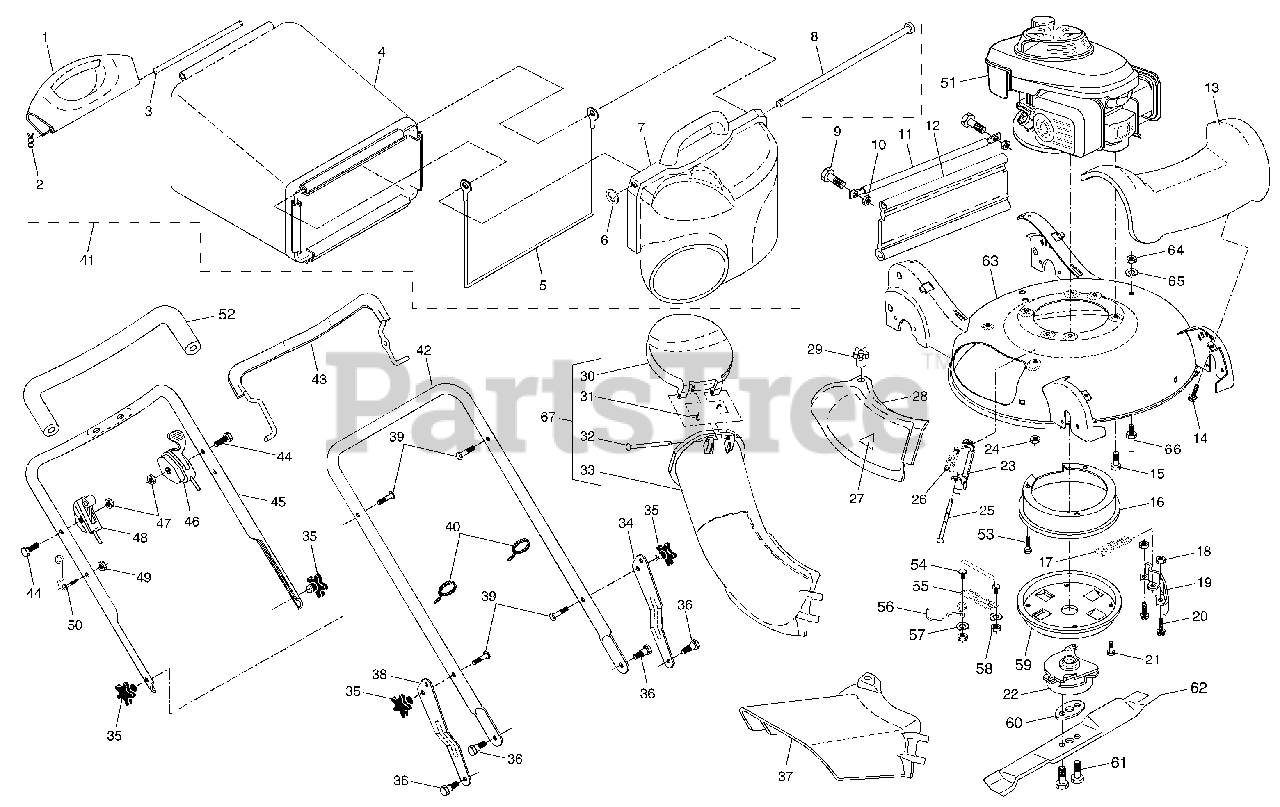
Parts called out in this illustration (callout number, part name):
1	Handle, Grassbag, Rear
2	Hairpin Cotter
3	Rod, Rear Handle, Grassbag
4	Grassbag
5	Frame, Grassbag
7	Door, Grassbag
8	Rod, Pivot
10	Nut, Hex
11	Tube, Rear Skirt
12	Skirt, Rear
13	Cover, Front
14	Screw, Hex Washer Head
15	Bolt, Engine Mounting
16	Belt Cover, Upper
18	Nut, Hex
19	Brake, Clutch
20	Bolt, Hex Head
21	Screw
22	Blade Brake / Clutch
23	Mounting Bracket, Mulcher Door
24	Nut, Hex
25	Rod, Hinge
26	Spring, Mulcher Door
27	Decal, Danger
28	Mulcher Door
30	Door, Discharge Chute
31	Spring, Door, Discharge Chute
32	Rod, Door, Discharge Chute
33	Discharge Chute, Plastic
34	Adjustment Bracket, Lower Handle, LH
35	Knob, Star
36	Bolt, Shoulder
37	Deflector, Discharge
38	Adjustment Bracket, Lower Handle, RH
39	Bolt, Handle
40	Wire Tie
41	Grassbag Assembly, Complete
42	Handle Assembly, Lower
43	Bail, Control
45	Handle Assembly, Upper
46	Blade Brake Control
48	Throttle Control
50	Rope Guide
52	Grip, Foam
53	Bolt, Engine
54	Link, Torque
56	Belt Keeper
57	Washer, Lock
59	Belt Cover, Lower
60	Spacer, Blade
61	Bolt, Hex Head
62	Blade, 21"
63	Kit, Housing
64	Nut, Hex 3/8-16
65	Washer, Lock
66	Stud, Belt Guide
67	Discharge Chute Assembly, Complete
